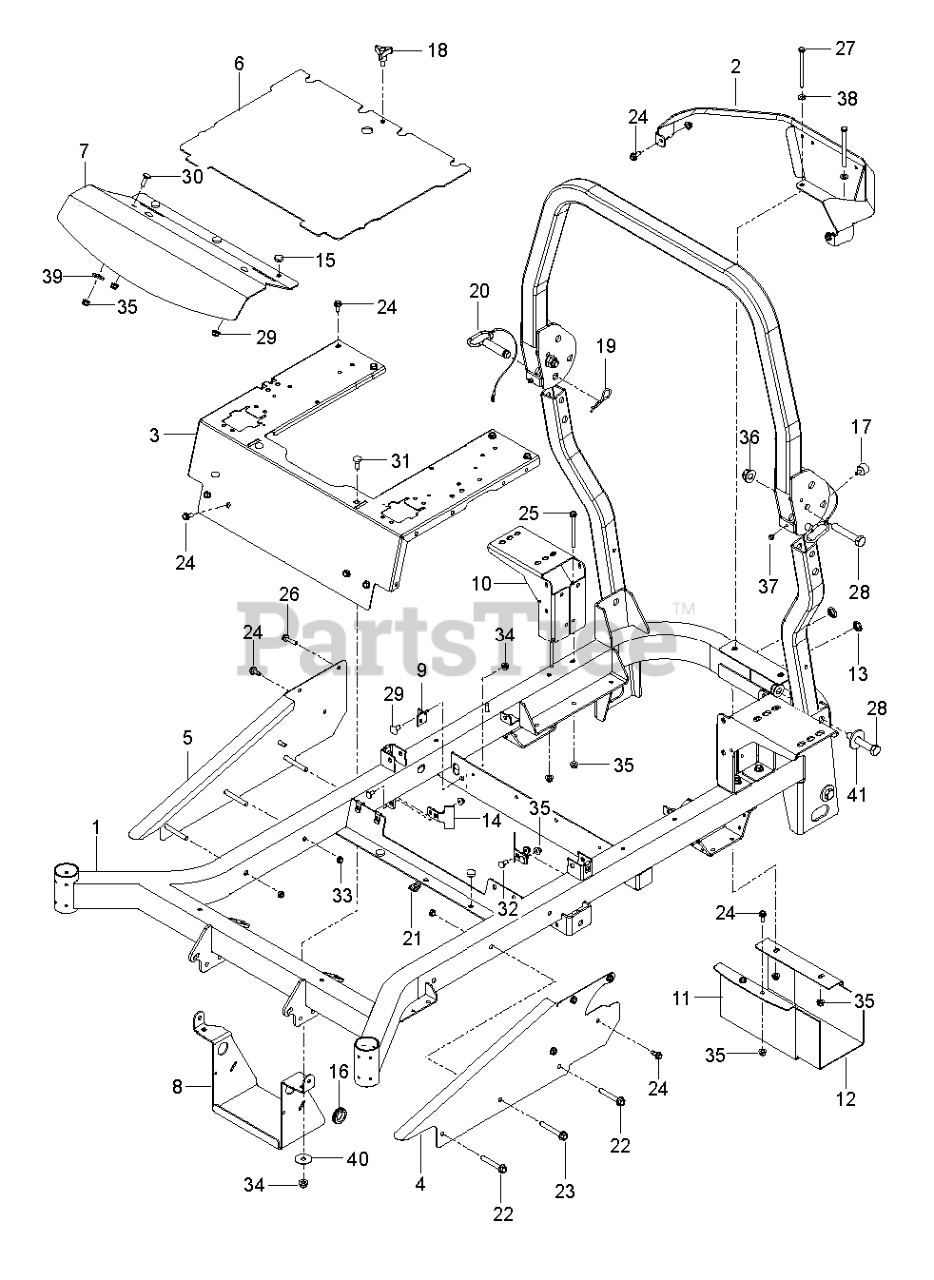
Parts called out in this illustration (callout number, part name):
1	KIT.FRAME.W/DECALS.X668
2	GUARD.PNT.REAR.MZ.GRAY
3	SUPPORT.PNT.SEAT.CONTROL.ORNG
4	SIDE.LT.ORANGE
5	SIDE.RT.ORANGE
6	PLATE, FLOOR W/DECALS
7	PLATE, FOOTREST
8	BRACKET.PNT.BATTERY.BLK
9	BRACKET.DAMPENER.BLACK
10	MOUNT, TANK, ZT BLK
11	SHIELD.MUFFLER.BLACK
12	HEAT SHIELD
13	CAP.PLUG.BP-1.BLACK
14	STOP, DECK, EZ+
15	GROMMET, BUMPER
16	RUBBER GROMMET
17	BUMPER, MALE STUD, 1/4-20
18	GSPW Knobs
21	U-CLIP 5/16-18 NUT RETAINER
25	BOLT.HEX.FLNG.5/16-18X3.75
32	GSPW Bolts
35	NUT HEXAGON FLANGE 5/16-18 ST
37	NUT HEXAGON 1/4-20 ST ZPB
38	WASHER 11/32 X 11/16 X 14 GA T
